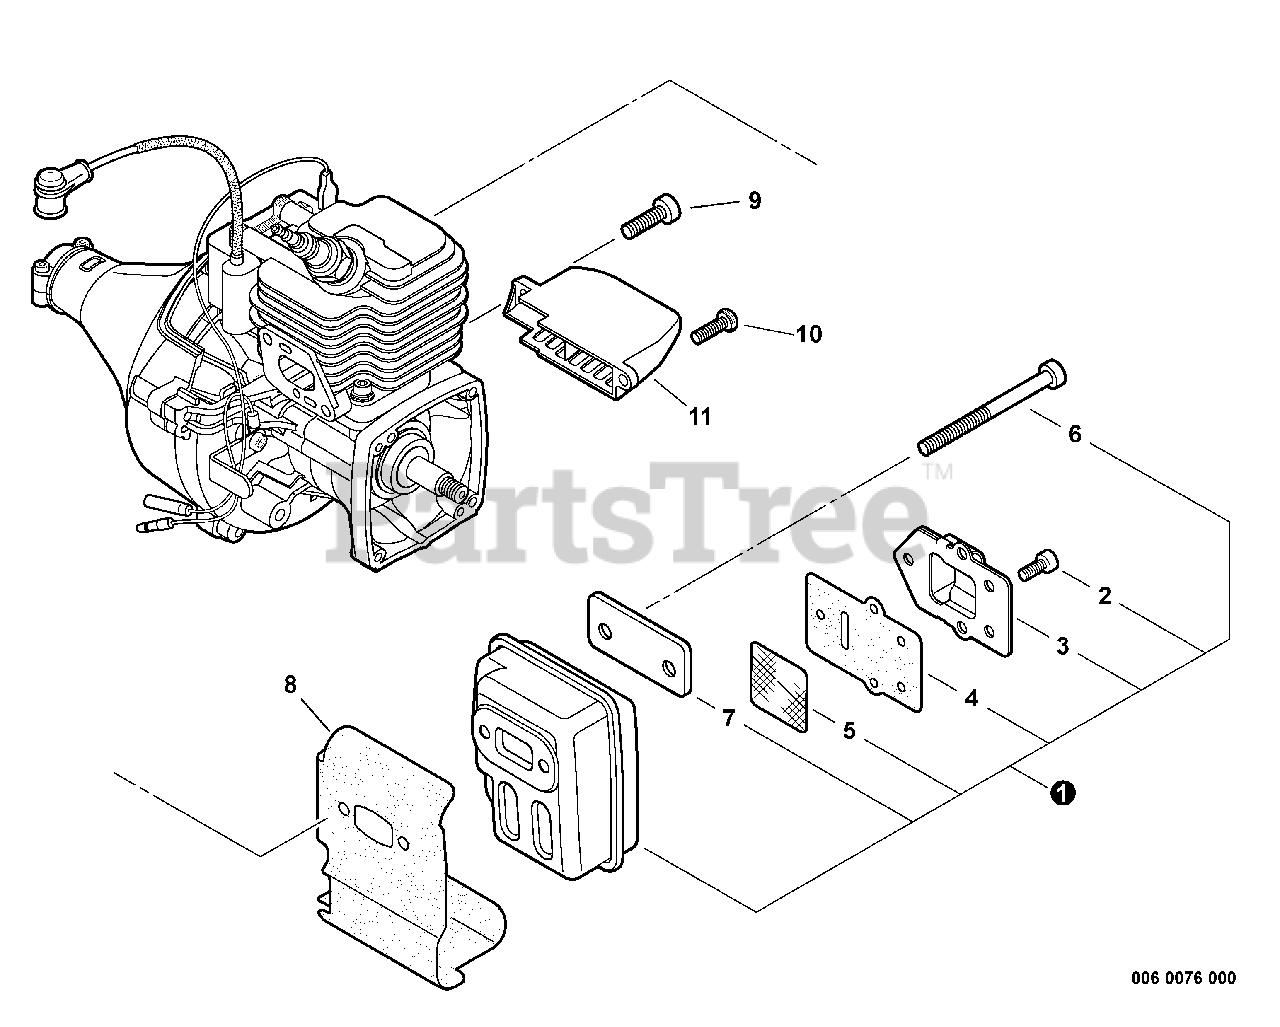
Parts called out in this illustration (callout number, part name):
1	MUFFLER ASSY
2	SCREW - 4X8
3	GUIDE, EXHAUST
4	GASKET, EXHAUST
5	SCREEN, SPARK ARRESTOR
6	SCREW - 5X55
8	SHIELD, EXHAUST
9	SCREW - 5X16
10	SCREW - 5X16
11	DUCT, AIR
